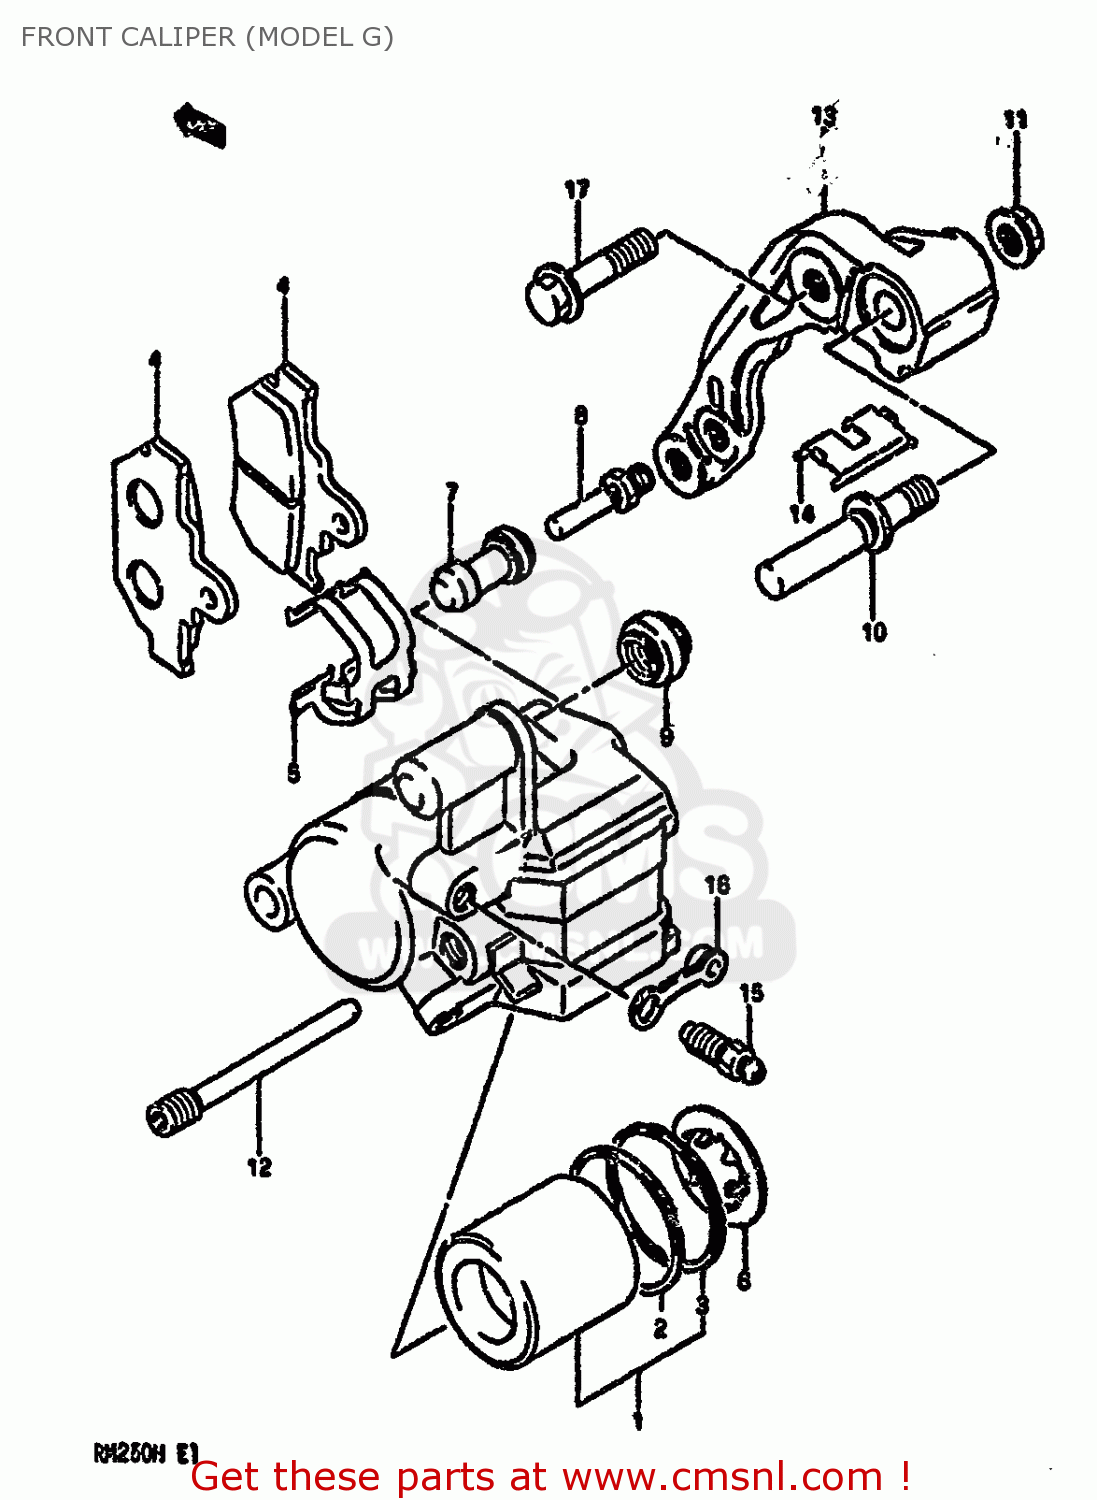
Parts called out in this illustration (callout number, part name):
1	PISTON SET,CALIPERS
2	SEAL
3	DUST SEAL,PISTON
4	PAD
5	SPRING
6	SHIM
7	BOOT
8	PIN,BOLT
9	BOOT
10	PIN,SLIDE
11	NUT,SLIDE PIN
12	PIN,HANGER
13	BRACKET
14	RETAINER
15	BLEEDER
16	CAP,BLEEDER
17	BOLT
